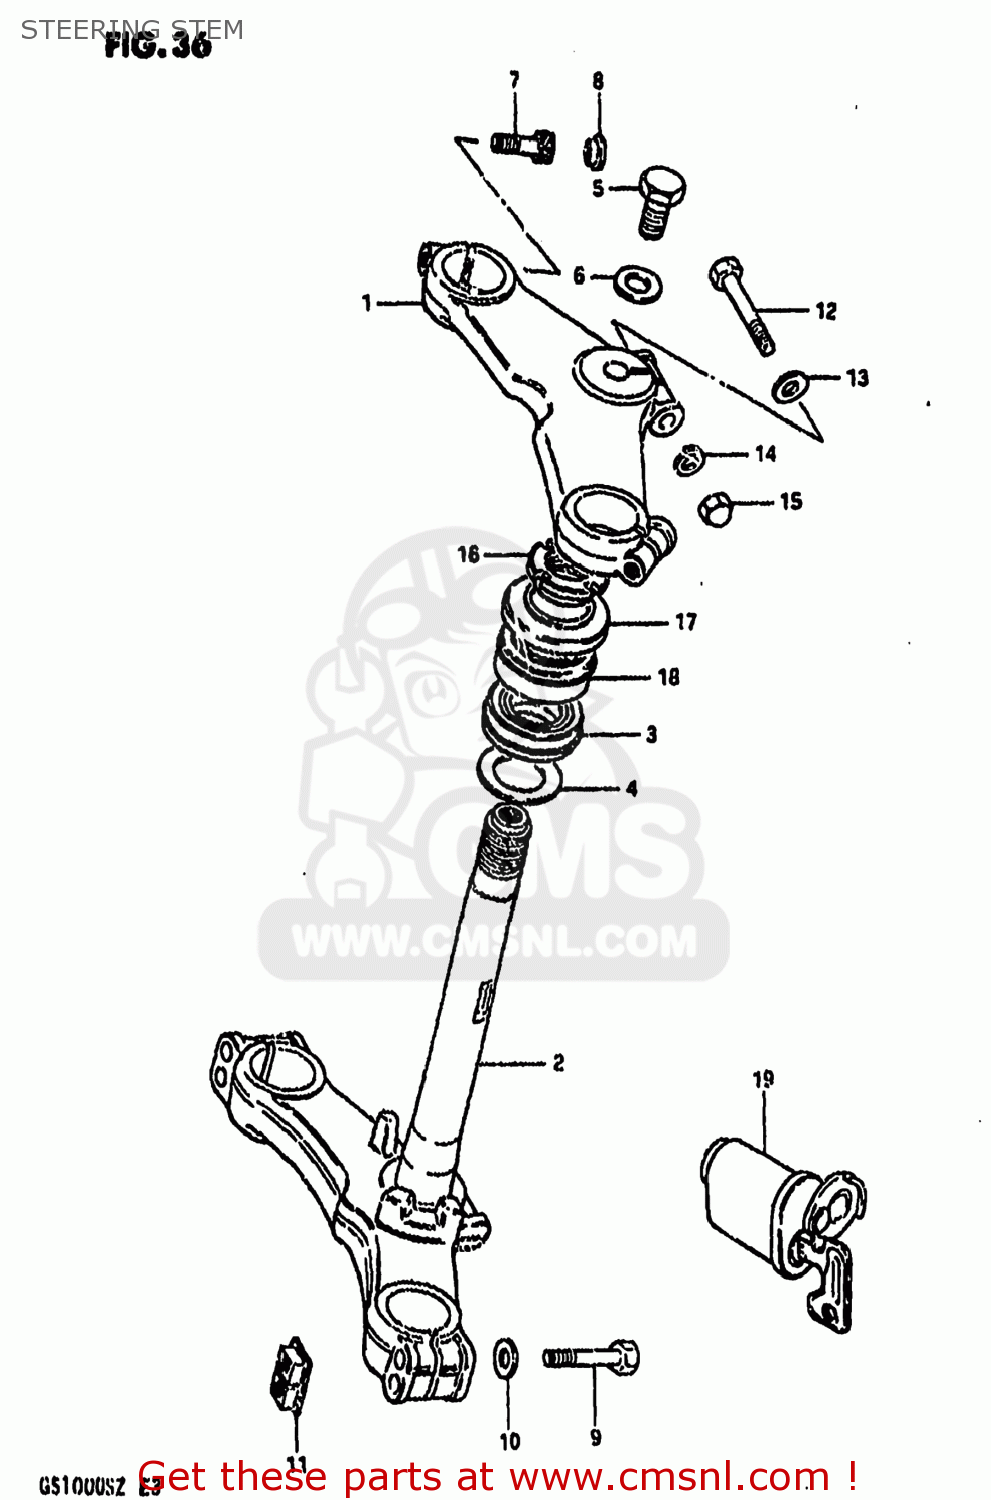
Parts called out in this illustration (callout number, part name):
1	STEM HEAD, STEERING (SILVER)
2	STEM, STEERING (SILVER)
3	BEARING
4	WASHER,THRUST
5	SUZUKI
6	SUZUKI
7	BOLT
8	CAP(OD:20)
9	BOLT 8X55
10	WASHER
11	NUT,FR FORK INNER TUBE
12	BOLT 8X50
13	WASHER
14	WASHER,LOCK,8.
15	NUT
16	NUT,STEERING STEM
17	DUST SEAL,STEERING UPR
18	TAPER,ROLLER BEARING
19	LOCK ASSEMBLY,STEERING (NEI
